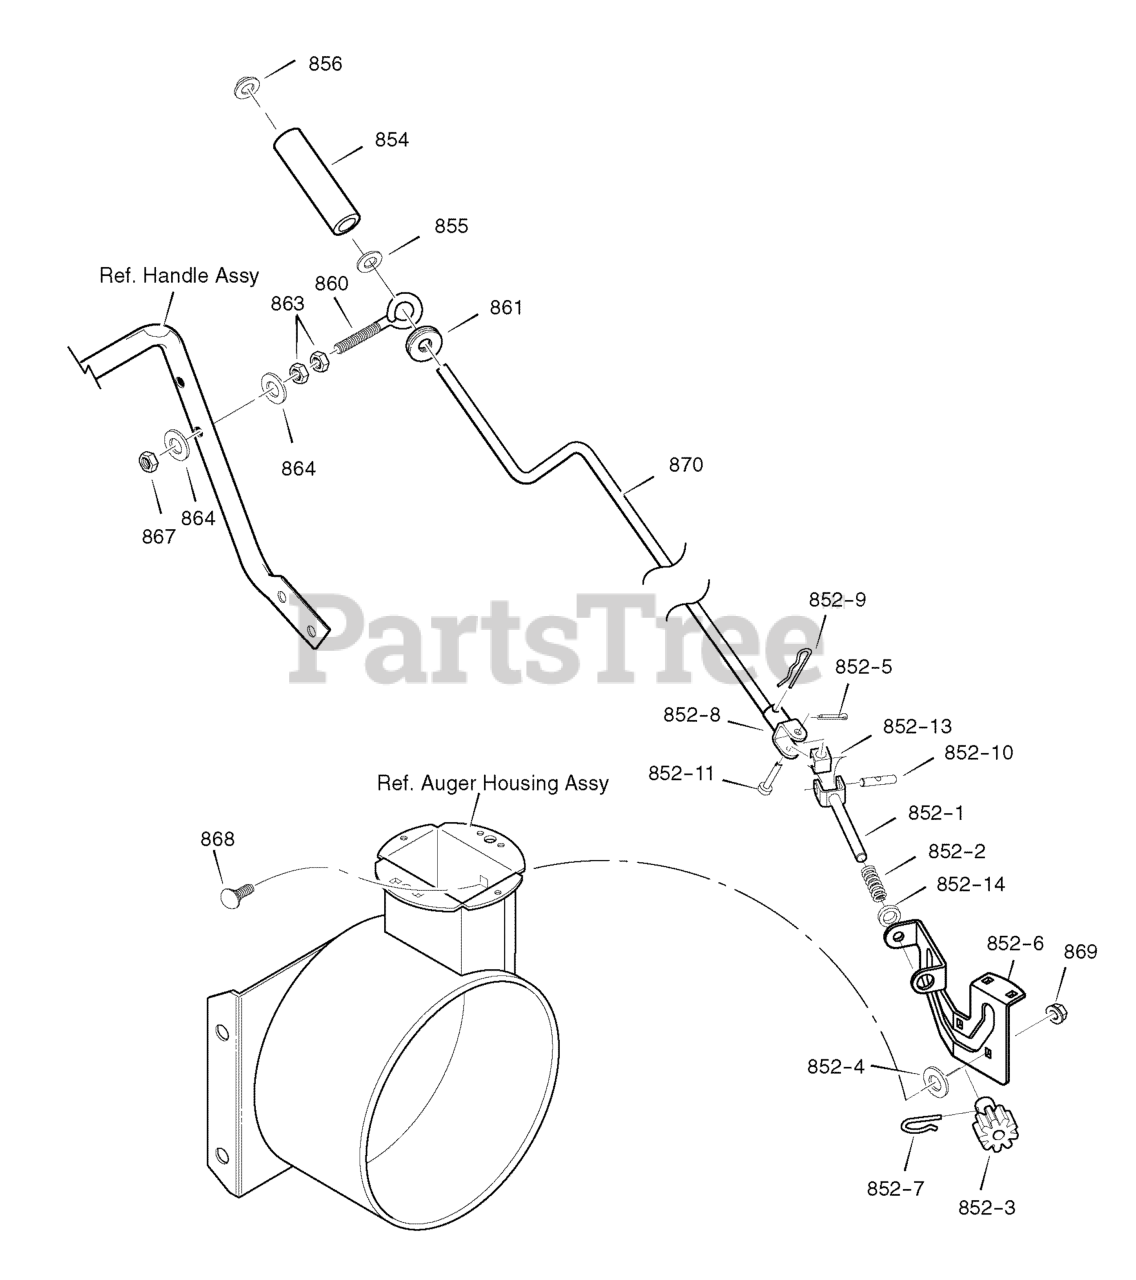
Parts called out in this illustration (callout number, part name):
852-1	ASSEMBLY, Yoke & Rod
852-2	SPRING, Compression
852-3	GEAR, Chute Rotation
852-5	PIN, Cotter
852-6	BRACKET, Gear
852-7	PIN, Hair
852-8	ASSEMBLY, Yoke Adapter
852-9	PIN, Hair
852-10	PIN, Universal Joint
852-11	PIN, Clevis
852-13	HOUSING, Universal
854	KNOB, Sleeve
856	NUT, Push-Pal, 3/8
860	EYE BOLT, 3/8 - 16 x 6
861	GROMMET, Eye Bolt
863	NUT, Hex Jam, 3/8 - 16
864	WASHER, Flat, 13/32
867	NUT, Hex Nylock, 3/8 - 16
868	BOLT, Cariage 1/4 - 20 x 1
869	NUT
870	CRANK ASSEMBLY, Chute
